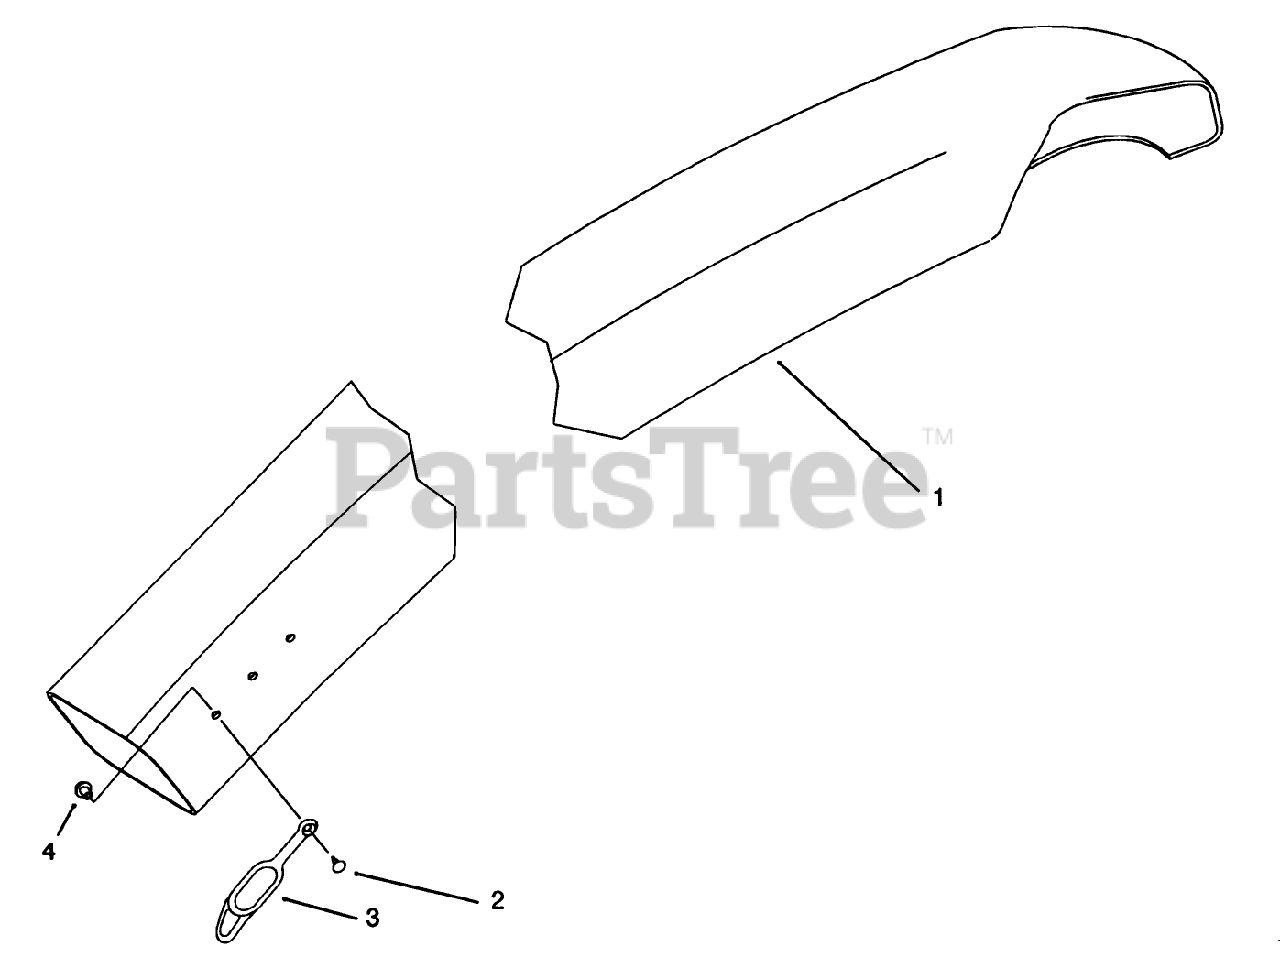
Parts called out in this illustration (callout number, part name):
1	CHUTE-DISCHARGE
2	FASTENER-PANEL
3	RETAINER-DUCT
4	SPACER-INTERLOCK
